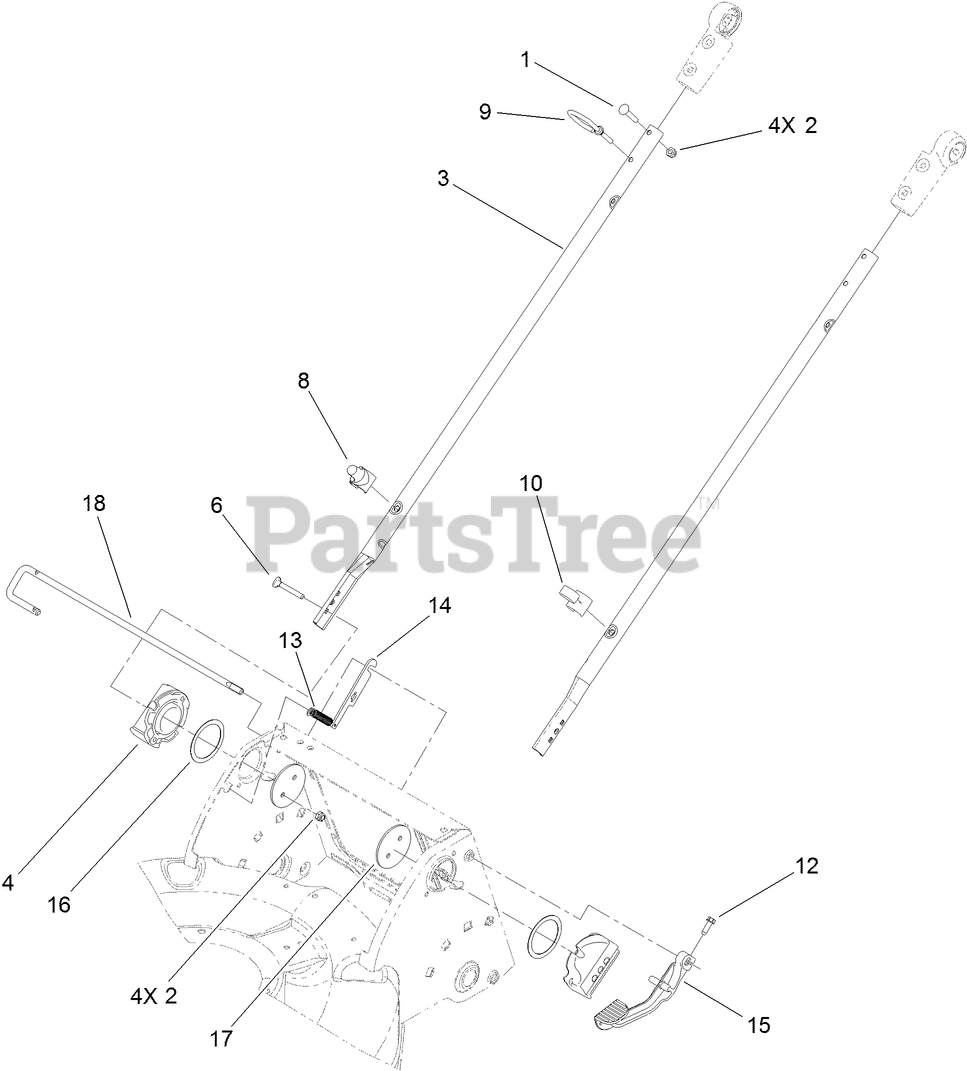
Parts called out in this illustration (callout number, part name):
1	SCREW-CARR
2	NUT-LOCK, NI
4	MOUNT-HANDLE
9	GUIDE-ROPE, UPPER
10	GUIDE-CABLE
12	SCREW-HWHTF
13	SPRING-EXTENSION
14	PLATE-ROD, RELEASE
15	LEVER-RELEASE
16	WASHER-NYLON
18	ROD-RELEASE, HANDLE
